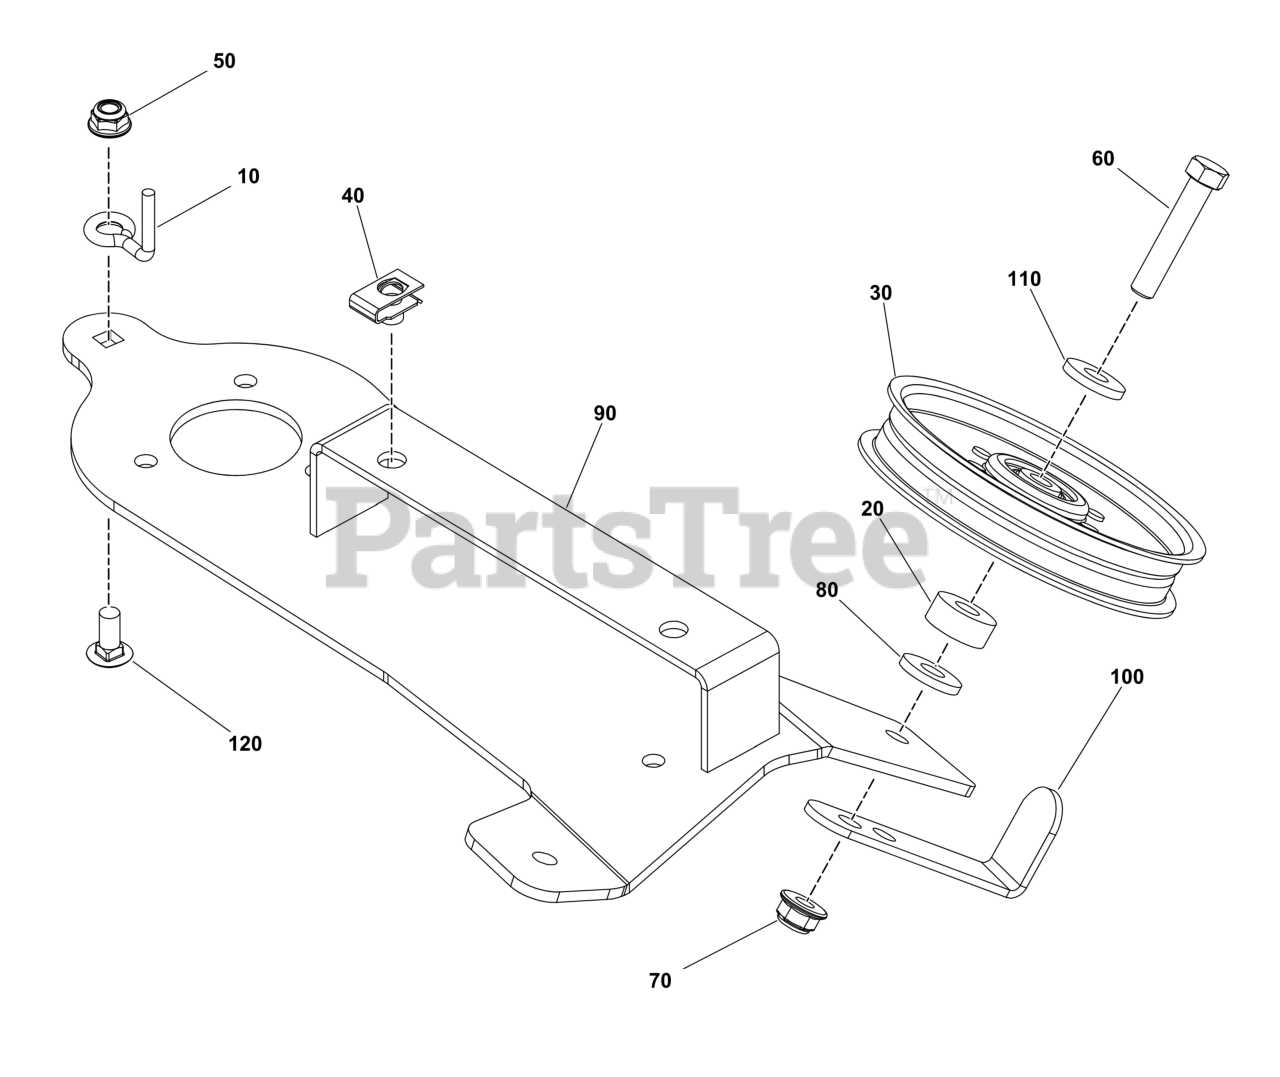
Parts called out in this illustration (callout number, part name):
30	PULLEY, Idler
40	BODY CLIP, 5/16-18 X
50	NUT
60	CAPSCREW, 3/8-16X2
70	NUT, 3/8-16 HEX NYLOCK
80	WASHER, 3/8" FENDER
90	ASSEMBLY, PULLEY PLATE, T-MAX (52,60,61)
110	WASHER
120	BOLT, 5/16-18 X 3/4",
